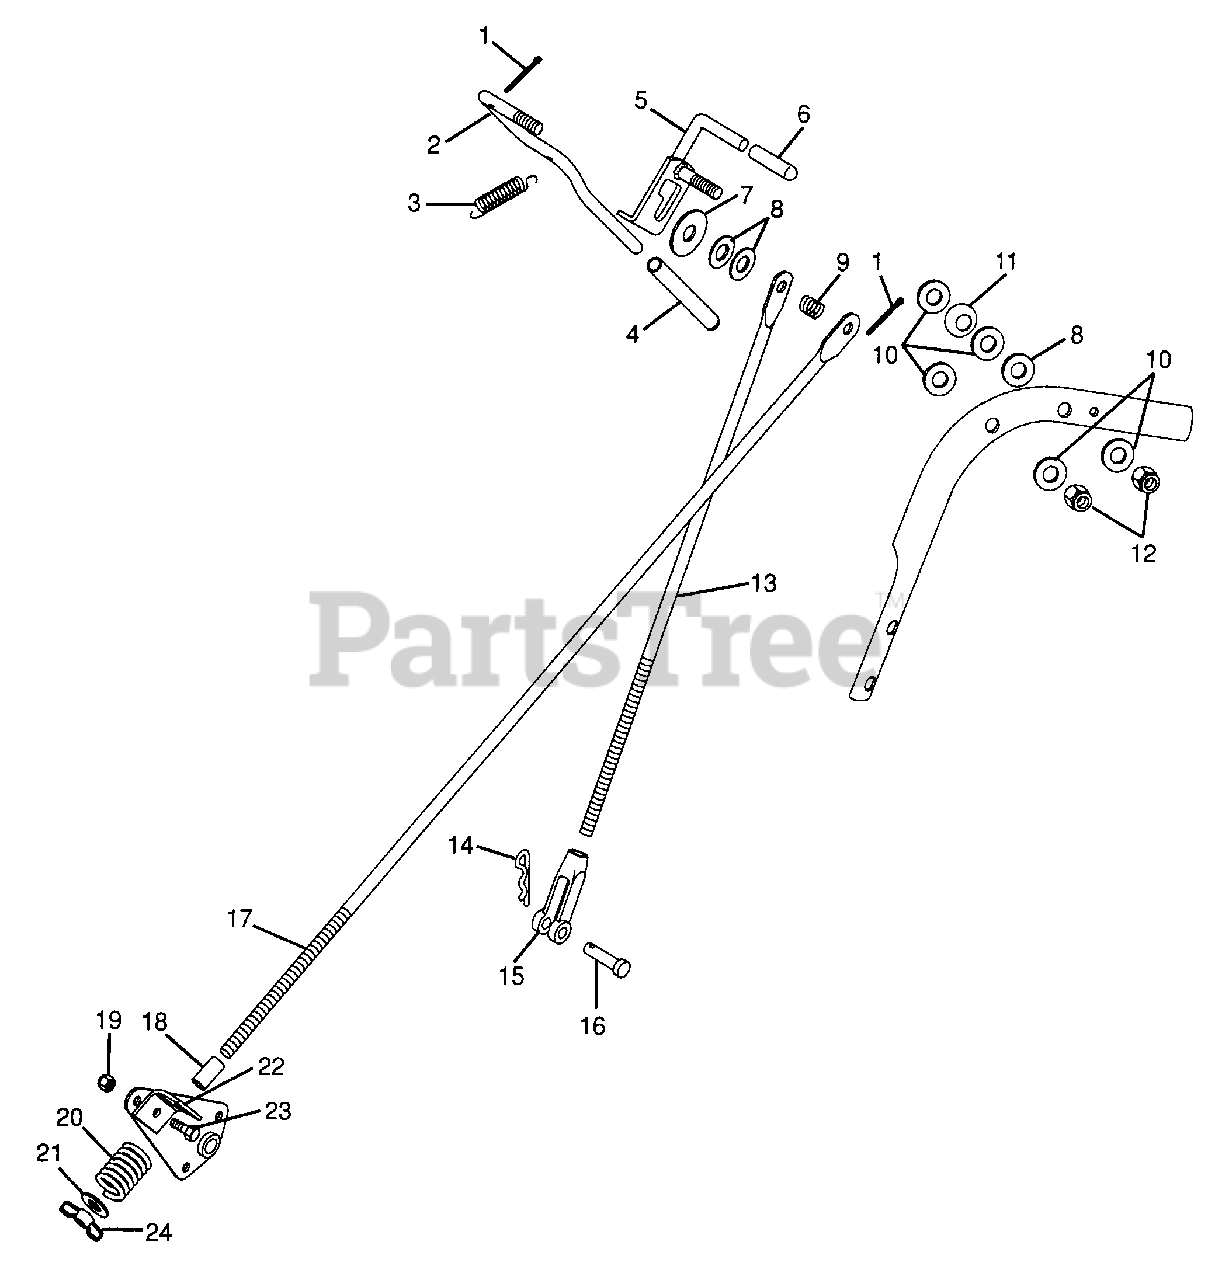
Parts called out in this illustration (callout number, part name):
1	Pin-Cotter .09 x .75
2	Lever, Hand Control
3	Spring-Tension .041 x .500 x 1.750
4	Grip, Hand Clutch Lever
5	Weldment, Clutch-Brake Lock
6	Tip-Brake Lock Lever
7	Washer-Flat-Steel .438 x 1.375 x .083
8	Washer-Flat-Steel .406 x .812 x .065
9	Spring-Compression .045 x .600 x .750
10	Washer-Flat-Nylon .375 x .75 x .060
11	Washer-Spring .375
12	Nut-Locking-Center .38-16
13	Rod, Clutch Actuating
14	Pin-Hair-Internal .08 x .18 x 1.18
15	Yoke .31-24 x 2.250
16	Pin, Clevis 5/16 x .812
17	Rod, Brake
18	Bushing .327 x .411 x 2.0
19	Nut-Locking-Center .25-20
20	Spring-Compression .125 x .78 x 1.00
21	Washer-Flat-Steel .344 x .688 x .065
22	Bracket, Brake Rod
23	Bolt-Hex .25-20 x .75 Grade 5
24	Nut-Nylock-Wing .312-18
